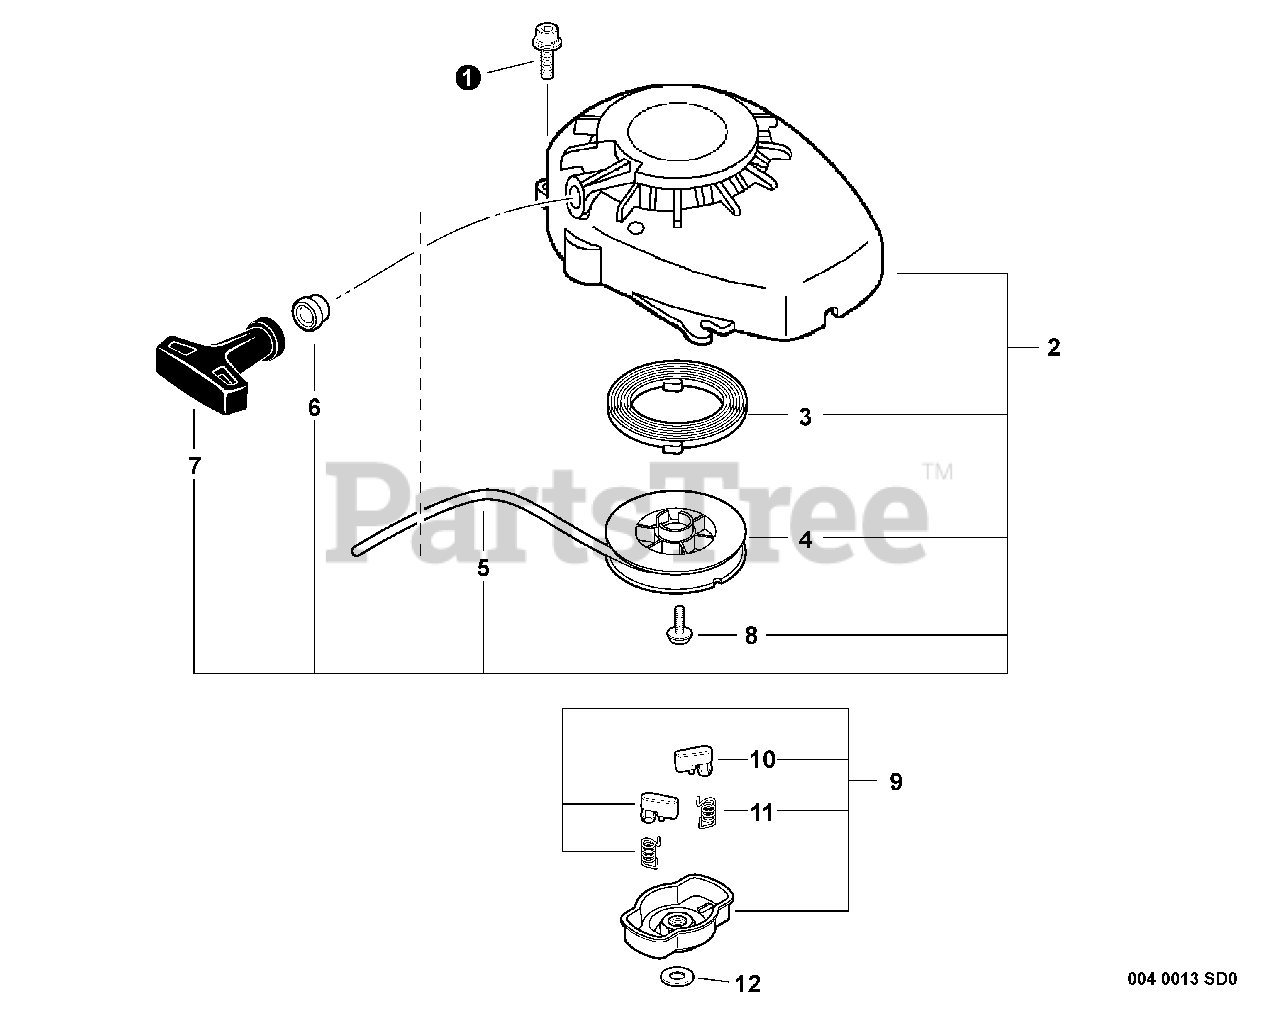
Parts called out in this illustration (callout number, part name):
1	BOLT 4×16
2	STARTER ASSY, RECOIL
3	SPRING, RECOIL
4	REEL, ROPE
5	ROPE, STARTER 3.0×1000
6	GUIDE, ROPE
7	GRIP, STARTER
8	SCREW
9	PAWL ASSY, STARTER
10	PAWL, STARTER - BLACK
11	SPRING, RETURN
12	WASHER, SPRING 8
